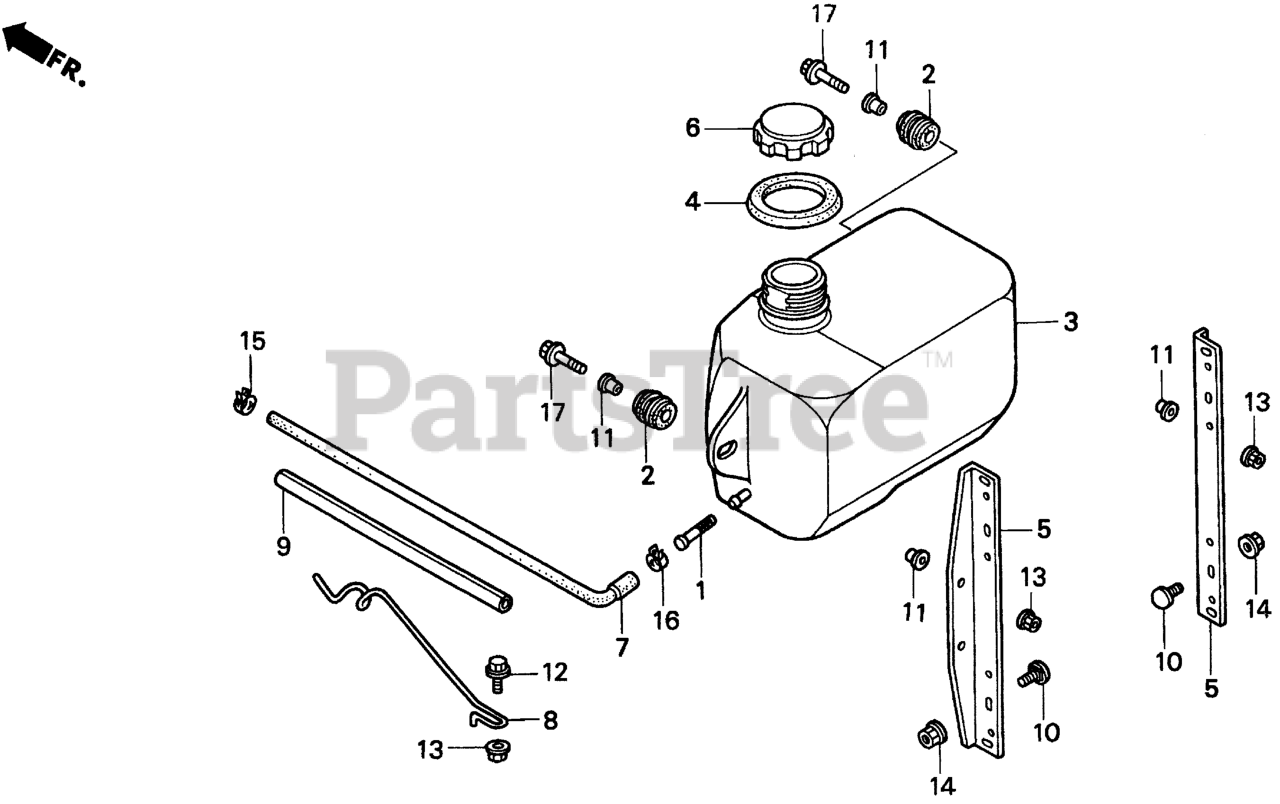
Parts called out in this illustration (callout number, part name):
1	FILTER, FUEL
2	RUBBER, TANK SETTING
3	TANK, FUEL
4	SEAL, FUEL FILLER NECK
5	PLATE, FUEL TANK MOUNT
6	CAP ASSY., FUEL TANK
7	TUBE, FUEL
8	HOLDER, FUEL HOSE
9	TUBE, CORRUGATED
10	BOLT, SPECIAL (9X15)
11	COLLAR, FUEL TANK
12	BOLT-WASHER (6X16)
13	NUT, FLANGE (6MM)
14	NUT, FLANGE (8MM)
15	CLIP, TUBE (D8)
16	CLAMP, TUBE (D10)
17	BOLT, FLANGE (6X35)
